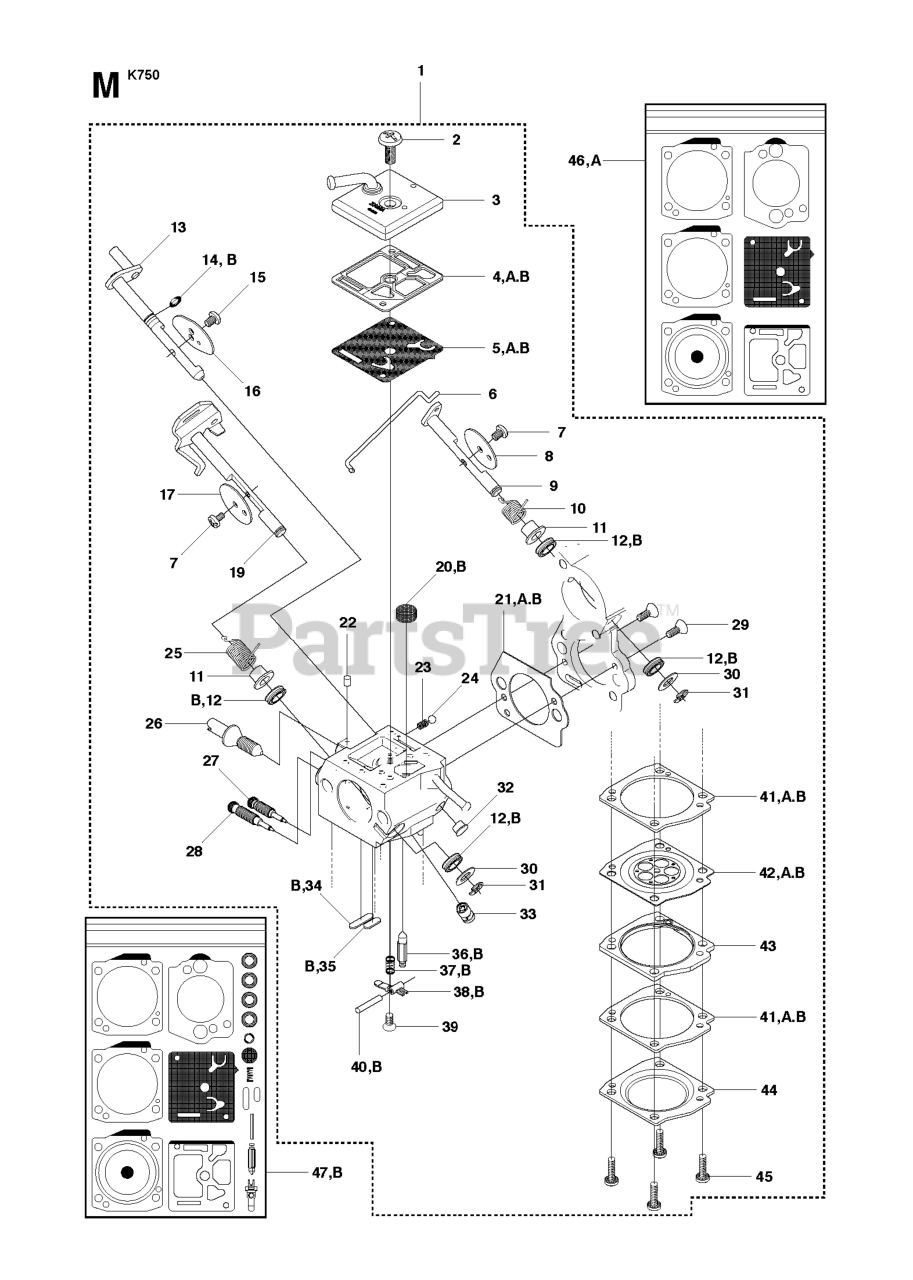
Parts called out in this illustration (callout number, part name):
1	CARBURETOR
3	PUMP COVER
5	DIAPHRAM PUMP
9	SHAFT ASSY
13	CHOKE SHAFT
17	THROTTLE FLAP
19	CHOKE CHAFT
26	SCREW - THROTTLE ADJUST.
33	NOZZLE ASSY CHECK VALVE
40	PIN RETAINING SCREW
41	GASKET, METERING
42	DIAPHRAM ASSY MET.
43	COVER, COMPENSATOR
44	COVER METERING
46	GASKET & DIAPHRAGM KIT
47	REPAIR KIT
